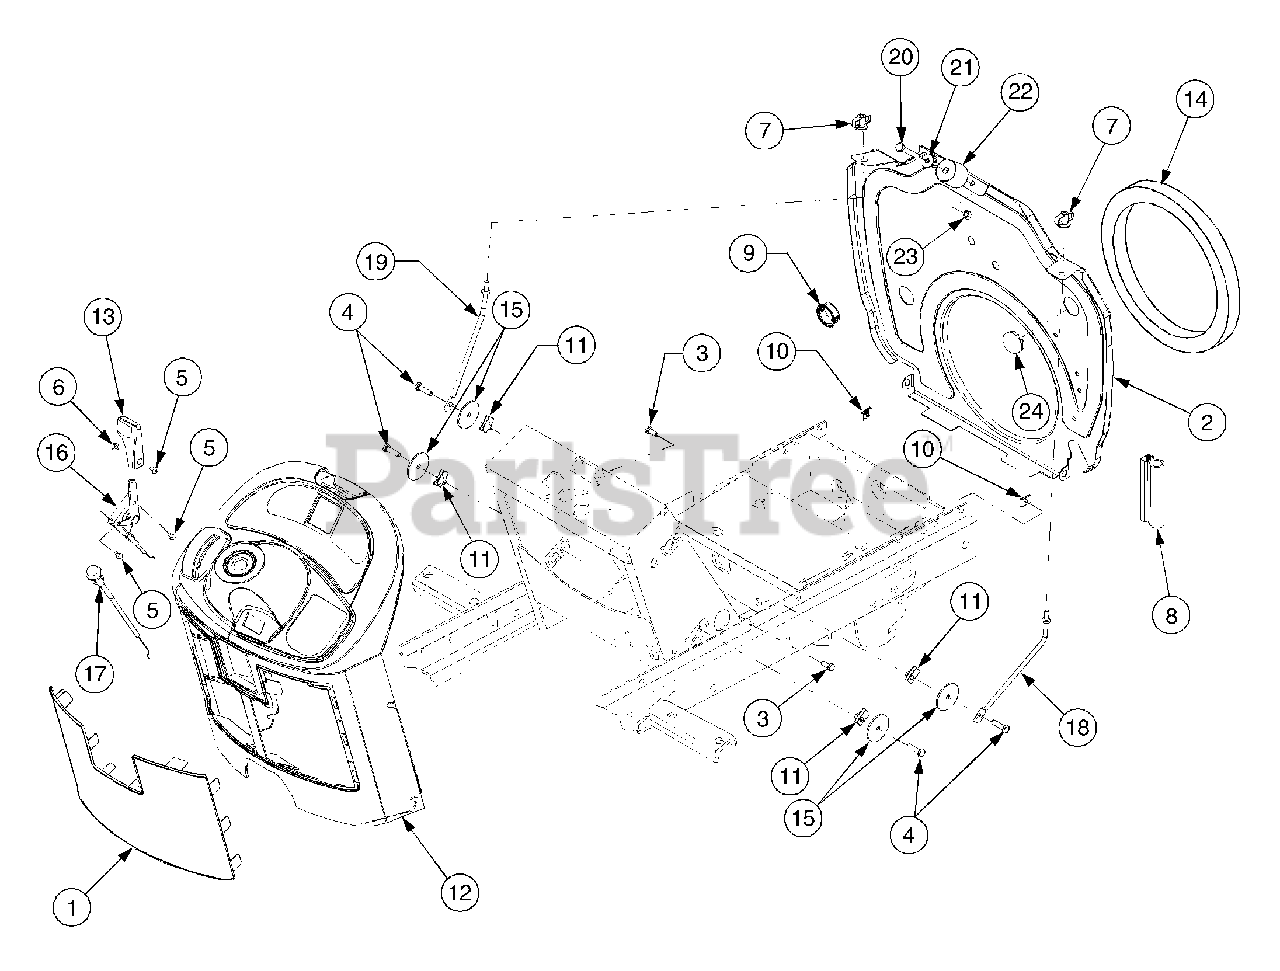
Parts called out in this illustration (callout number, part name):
4	Screw, Hex Cap, 1/4-20 x 1.0
5	Screw, Cross Rec Trus, #8-32 x .38
6	Nut, #8-32
7	Nut, Wing w/Bell Washer 1/4-20
8	Seal, Push On Trim
9	Bushing, Snap, 7/8 ID
10	Nut, U-Type Speed, 1/4-20
11	Nut, U-Clip, 1/4-20
12	Panel, Dash
13	Knob, Throttle
14	Seal Ring, Foam
15	Washer, Flat, .285 x 1.75 x .10
16	Control, Throttle
17	Control, Choke
18	Rod, RH Mounting
19	Rod, LH Mounting
20	Screw, Hex Cap,1/4-20 x 1.75 GR5
21	Washer, Flat, .283 x .75 x .030
22	Roller, Hood Latch
23	Nut, Hex Sems, 1/4-20
24	Plug. Button
